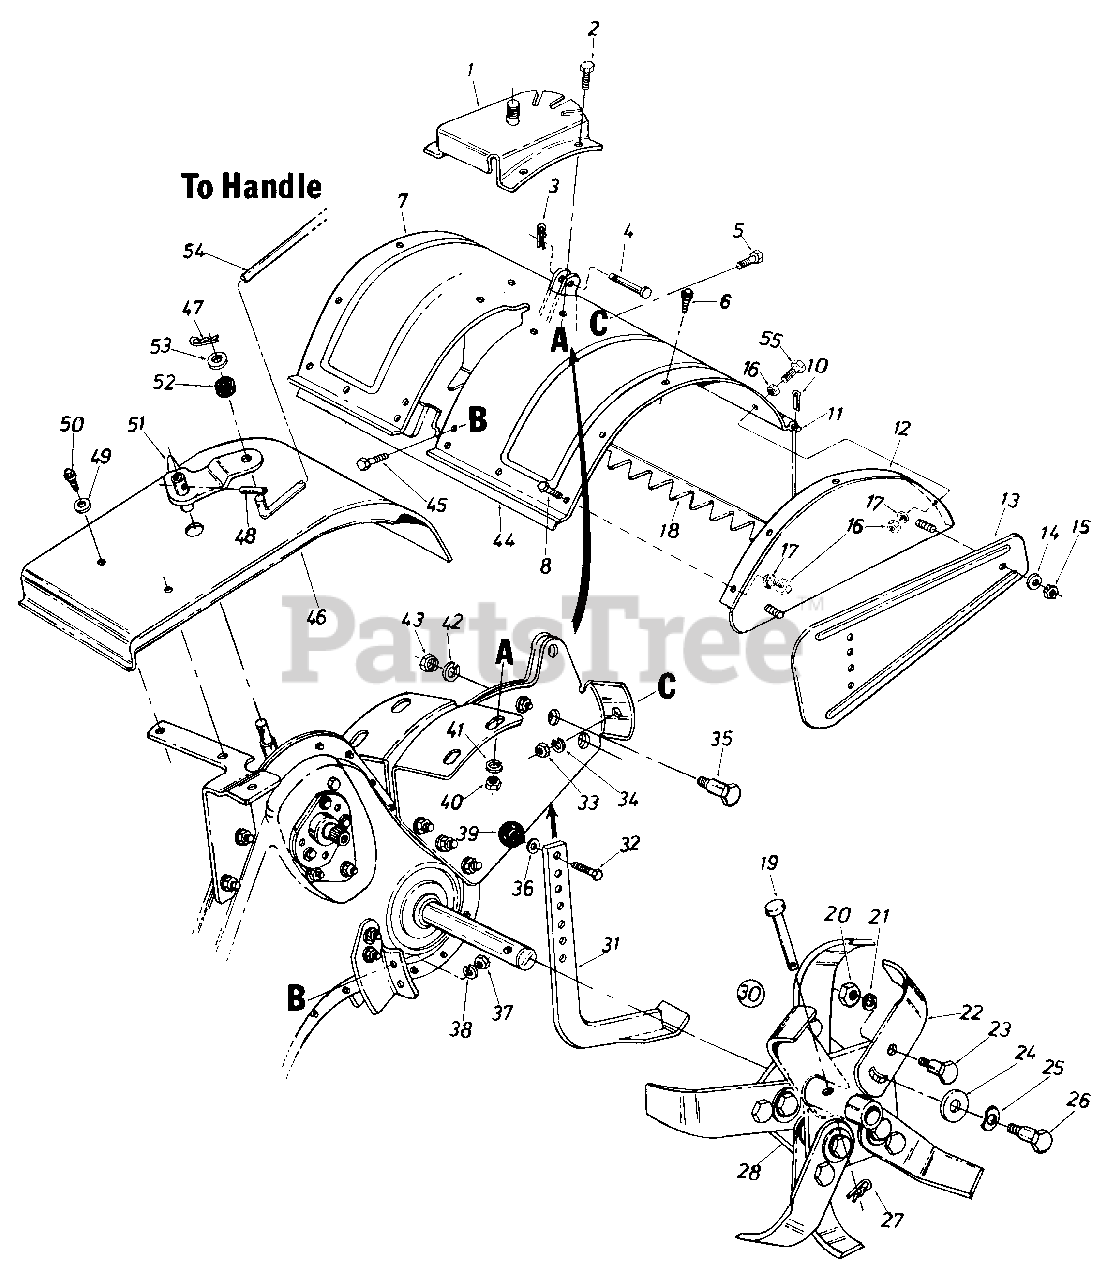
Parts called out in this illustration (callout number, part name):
1	BRACKET ASSY
2	SCREW-HEX 3/8-16 X .75
3	PIN-INTERN COT
4	PIN-CLEVIS 3/8 X 1.620
5	SCREW-HEX 5/16-18 X .75
6	SCREW-TAP 5/16-18X.62
10	PIN-COTTER-3/32 DIA X .75
11	ROD-TILLER FLAP
15	NUT-HEX 5/16-18
16	NUT-HEX 5/16-18
17	WASHER-LOCK-5/16
19	PIN-CLEVIS 3/8 X 1.620
20	NUT-HEX 3/8-24
21	WASHER-HDL 3/8
23	SCREW-SHLD 3/8-24 X 3/4 LG
24	WASHER-FL .51IDX1.50ODX.075
25	WASHER-BELL .515X1.4
26	SCREW-SHLD
27	PIN-COTTER
32	SCREW-HEX 3/8-16 X .75
33	NUT-HEX 5/16-18
34	WASHER-LOCK-5/16
35	SCREW-SHLD .500 DIA X .660
36	WASHER-FL-.385 ID X .62 OD X .033
37	NUT-HEX 5/16-18
38	WASHER-LOCK-5/16
39	KNOB-BALL 1-3/8 " DIA.
40	NUT-HEX 3/8-16
41	WASHER-LOCK-3/8
42	WASHER-LOCK-3/8
43	NUT-HEX 3/8-16
45	SCREW-HEX 5/16-18 X .75
46	COVER-SHIFT
47	PIN-INTERN COT-5/16 DIA
48	PIN-SPRING SPIR 3/16 X 1.00
49	WASHER-FL
50	SCREW-HEX WASH SF TAPP
51	CRANK ASSY-SHIFT
52	WASHER-RUBBER
53	WASHER-FL-.406 ID X 1.25 OD
54	ROD-CONTROL
55	SCREW-HEX 5/16-18 X 1.25
